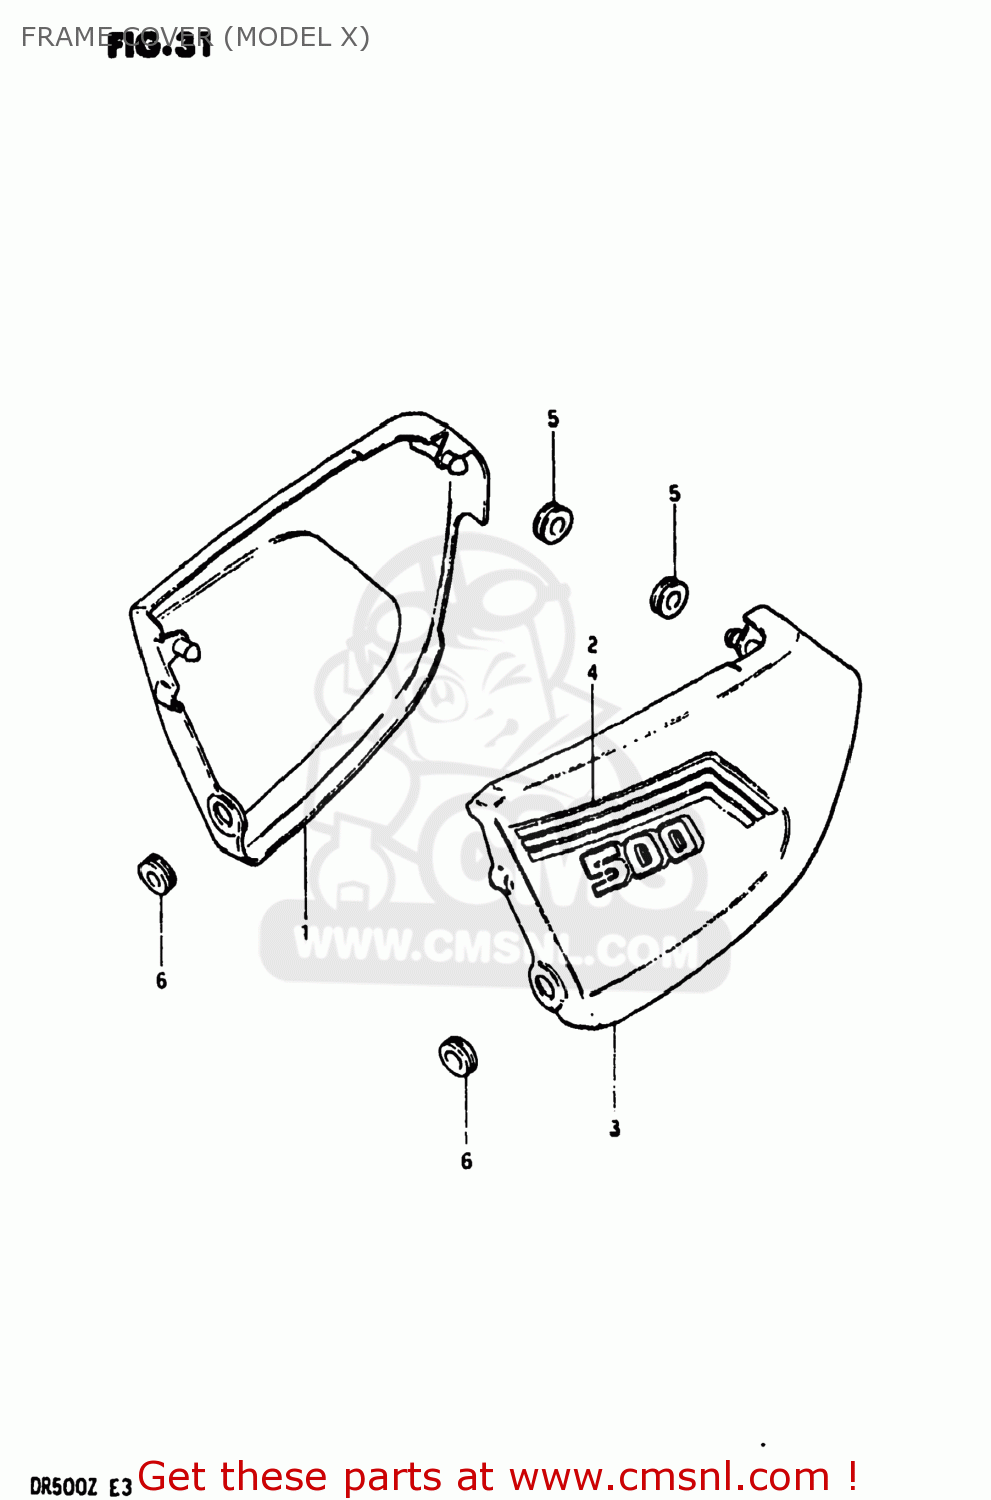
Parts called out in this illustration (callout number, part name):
1	COVER,FRAME,RIGHT
2	TAPE,FRAME COVER,RIGHT
3	COVER,FRAME,LEFT
4	TAPE,FRAME COVER,LEFT
5	CUSHION
6	CUSHION
